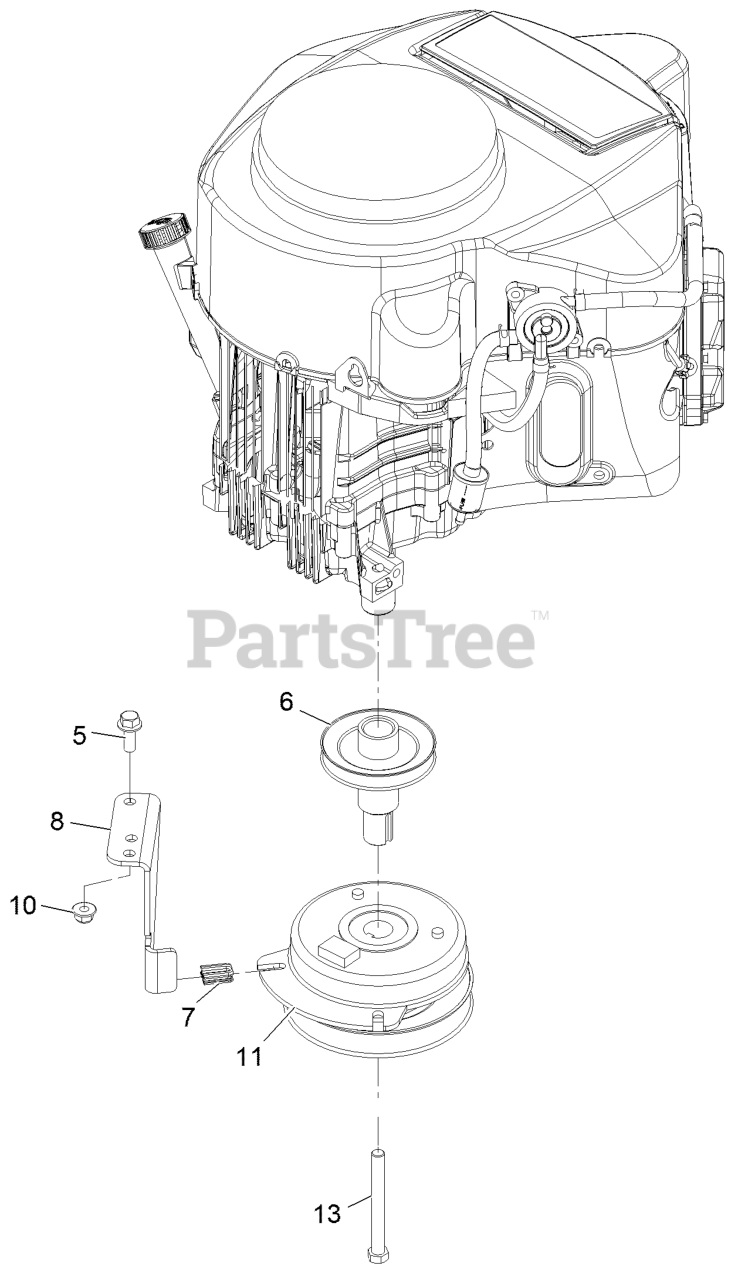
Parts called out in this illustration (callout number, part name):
5	SCREW-HHF 3/8-16 X 1
6	PULLEY-ENGINE
7	ISOLATOR-CLUTCH
8	STOP-CLUTCH
10	NUT-HF, NI
11	CLUTCH-PTO
13	SCREW-HH
